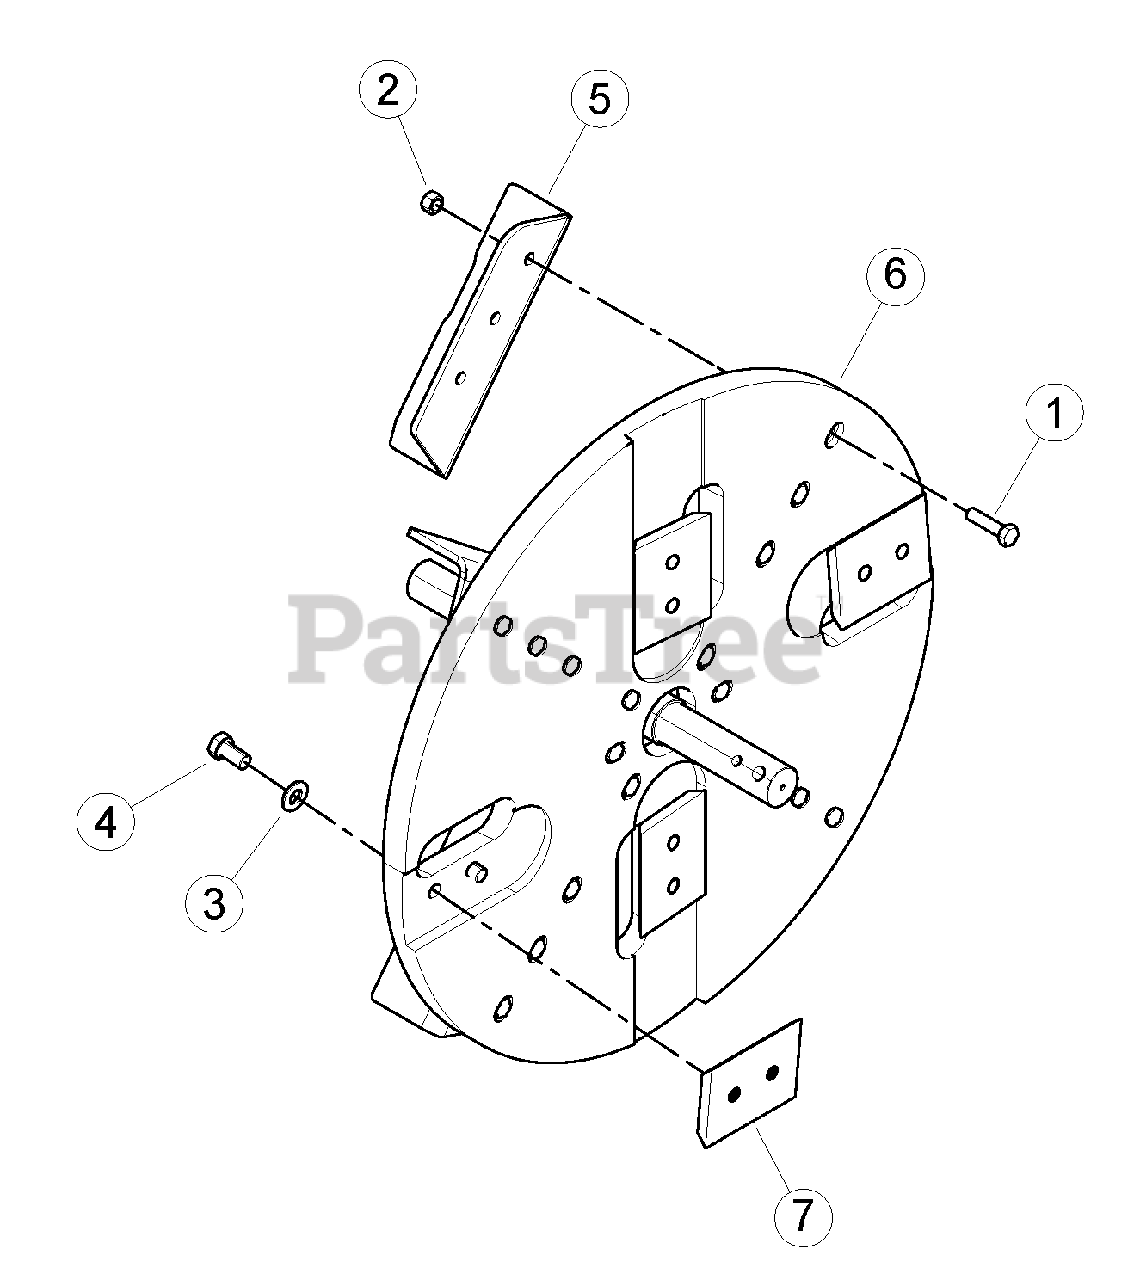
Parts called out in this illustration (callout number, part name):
1	BOLT, 1/2 X 2 HEX HD GR5 ZP
2	NUT, 1/2 CENTERLOCK GRB ZP
3	WASHER, 5/8 SAE HARDENED
4	BOLT, M16 X 2.0 X 30 HEX HD W/ PATCH
5	KIT, BIG CHIPPER FORMED PADDLES
6	ASSEMBLY, 9 INCH CHIPPER ROTOR
7	KIT, CHIPPER BLADE
